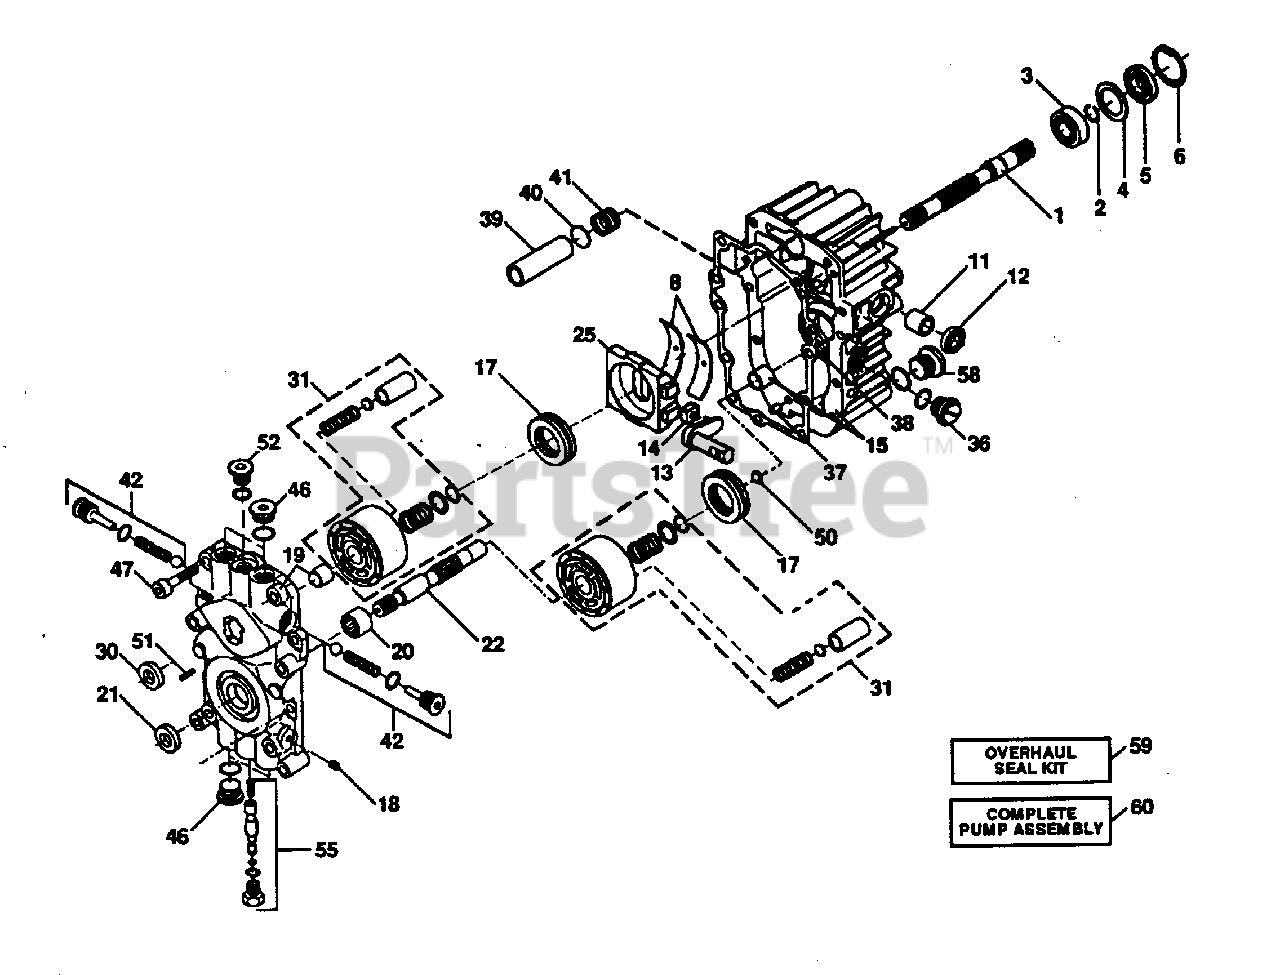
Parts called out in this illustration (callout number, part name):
1	Shaft, Pump
2	Ring, Retaining
3	Bearing, Ball
5	Seal, Lip
6	Ring, Retaining
8	Bearing, Cradle
11	Bearing, Journal
13	Arm, Trunnion
14	Guide, Slot
15	Housing Kit, Transmission
17	Bearing, Thrust, Ball
19	Center Section Kit
20	Bearing, Needle
21	Seal, Lip
25	Swashplate, Variable
31	Block Kit, Cylinder
36	Plug, Plastic
37	Pin, Stainless, Headless
38	Gasket, Center Section
39	Filter
40	Washer, Thrust
41	Spring, Helical, Compression
42	Check Valve Kit
46	Plug, Stainless, Threaded
47	Screw, Socket Head, Cap
50	Washer, Thrust
51	Pin, Spiral
52	Plug, Stainless, Threaded
55	Bypass Valve Kit
58	Plug, Stainless, Threaded
59	Overhaul Seal Kit,BDU-10
60	Pump Assembly, Complete
